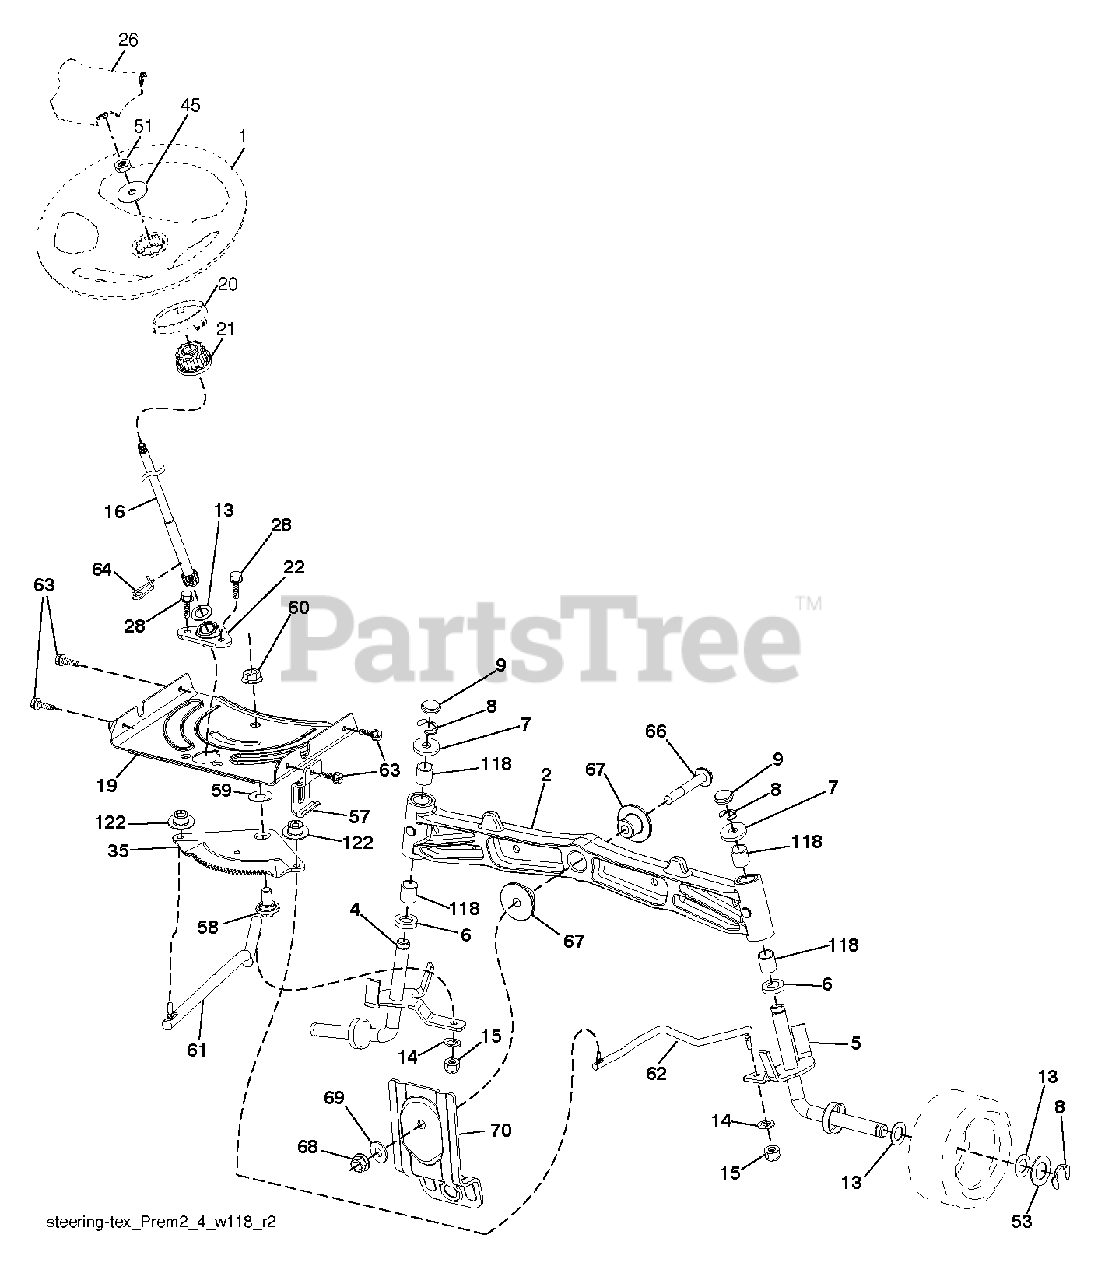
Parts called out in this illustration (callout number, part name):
1	WHEEL.STEERING.STDSRR.BLK/OV
2	AXLE.SVC.ASM CAST IRON.TEX
4	SPINDLE.WELDED.LH.16"TEX
5	SPINDLE.WELDED.RH.16"TEX
8	RING CLIP
9	CAP.SPINDLE
14	WASHER, LOCK 3/8
15	NUT CROWNLOCK 3/8-24
16	SHAFT.STEER.STEALTH.DD
19	PLATE.STEER.DDL.NLT/NG
21	ADAPTER, WHEEL STNG..
22	STEERING.SUPT.LOWER.
26	CAP.WHL.STRNG.STDSRRD.SRS.BLK
28	SCREW, 3/8-16X3/4
35	GEAR.SECTOR.PLATE.DDL.
45	WASHER 9/16"ID, 2 3/8"OD
51	NUT.HEX.1/2-20
53	WASHER.HARDENED
57	BRKT.UPSTOP.GT/LT.TEX
58	BOLT.SHOULDER.SECTOR.P
59	WASHER.THURST.SECTOR.S
60	NUT FLANGE LOCK 5/8-11
61	DRAGLINK.LH.BALLSTUD.D
62	DRAGLINK.RH.BALLSTUD.D
63	SCREW
64	RETAINER.CLIP.SPRING.S
66	BOLT HEX FGHD 7/16-14 X 3 SERR
67	BUSHING.PM.FRONT AXLE
68	NUT.LOCK.FLANGE.7/16
69	WASHER.1.5X.505X.118
70	BRKT.DECK.SUSPENSION.F
118	BUSHING, AXLE CAST
